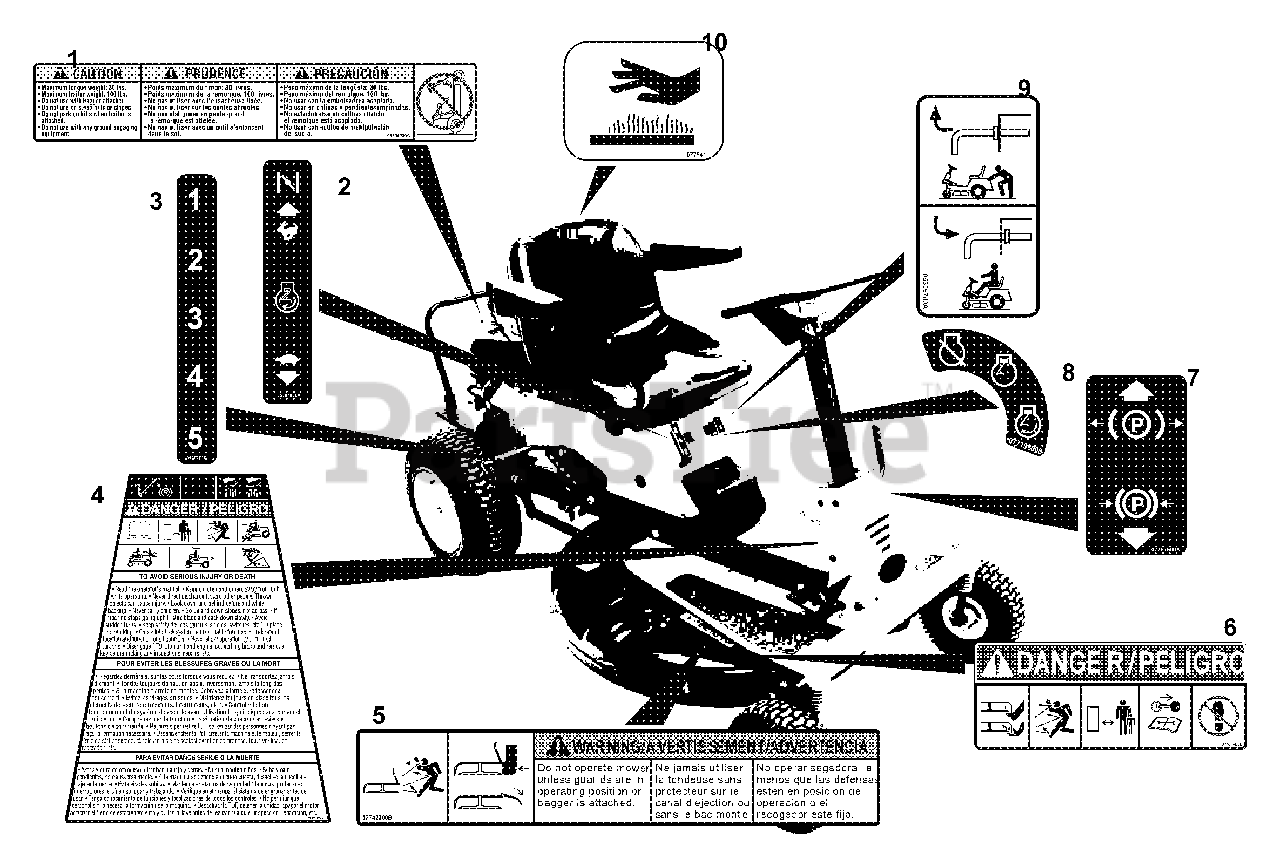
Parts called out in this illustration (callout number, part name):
1	Decal, Trailer Hitch
2	Decal, Throttle
3	Decal, 5 Position Cut Height
4	Decal, Rear Engine Rider Warning
5	Decal, Warning
6	Decal, Mower Pan Danger
7	Decal, Parking Brake Lever
8	Decal, Ignition
9	Decal, Transmission Disconnect
10	Decal, Hot Surface
